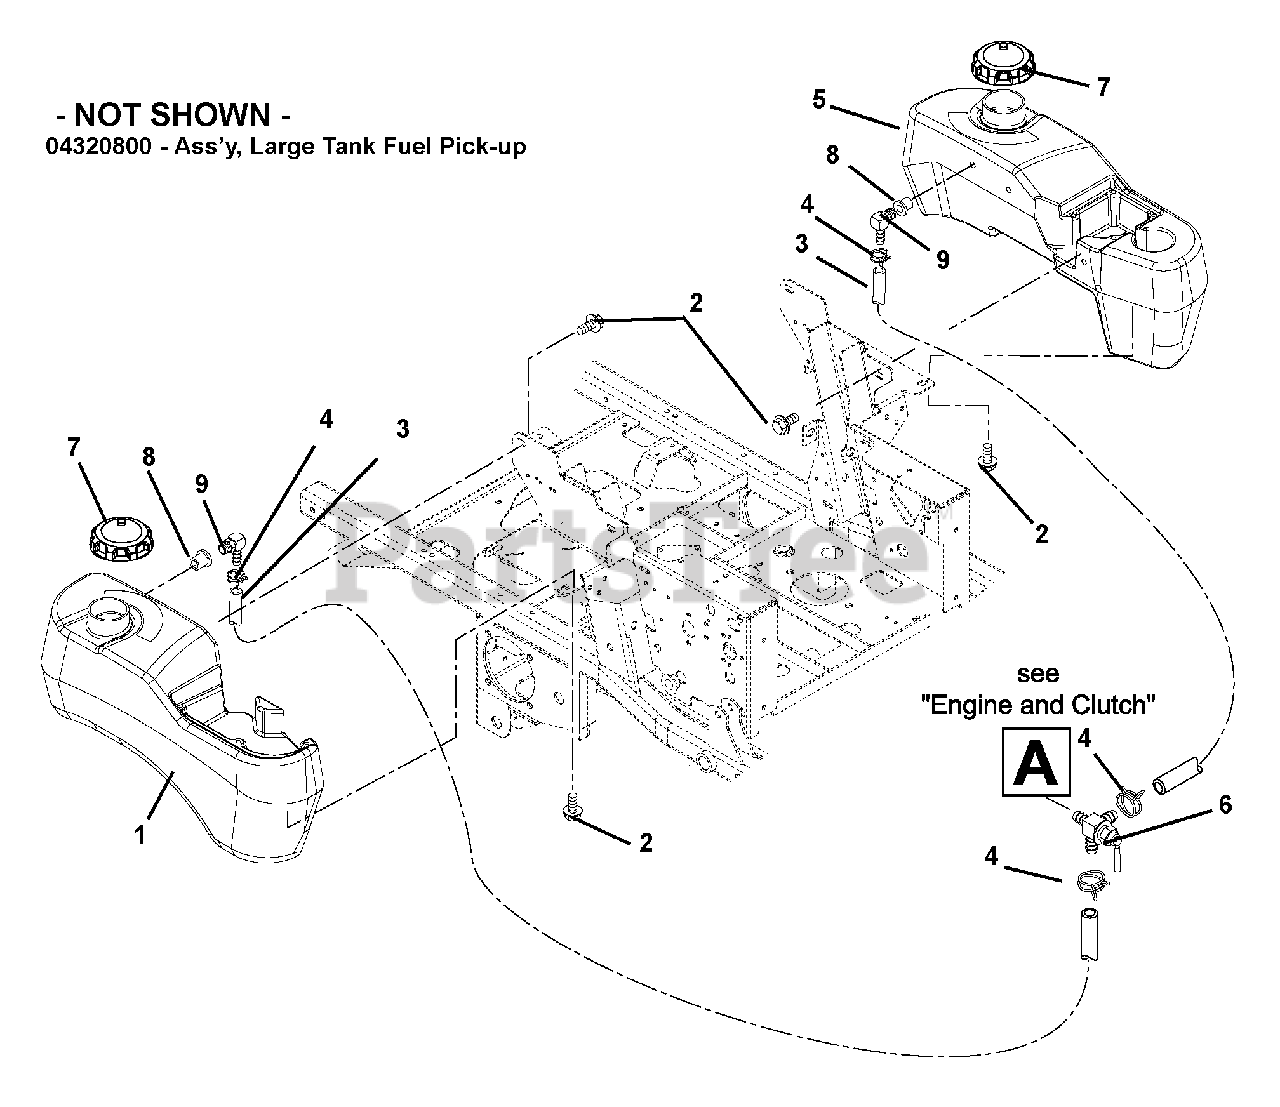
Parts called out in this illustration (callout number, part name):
1	Tank, Fuel - Right Hand
2	Bolt, SEMS .31-18 x .62
3	Gas Line, Bulk .25 I.D. (2 at 42 in.) (992111, 115, 127, 128, 129, 131, 132, 133, 145)
3	Gas Line, Bulk .25 I.D. (2 at 42 in.) (992113, 117, 124, 130, 134, 135, 139)
4	Clamp, Hose Wire .49/.51 x .116
5	Tank, Left Hand Fuel (EYE-Q)- 200 Series
6	Valve, Fuel
7	Cap, Gas
9	Tank Fitting
